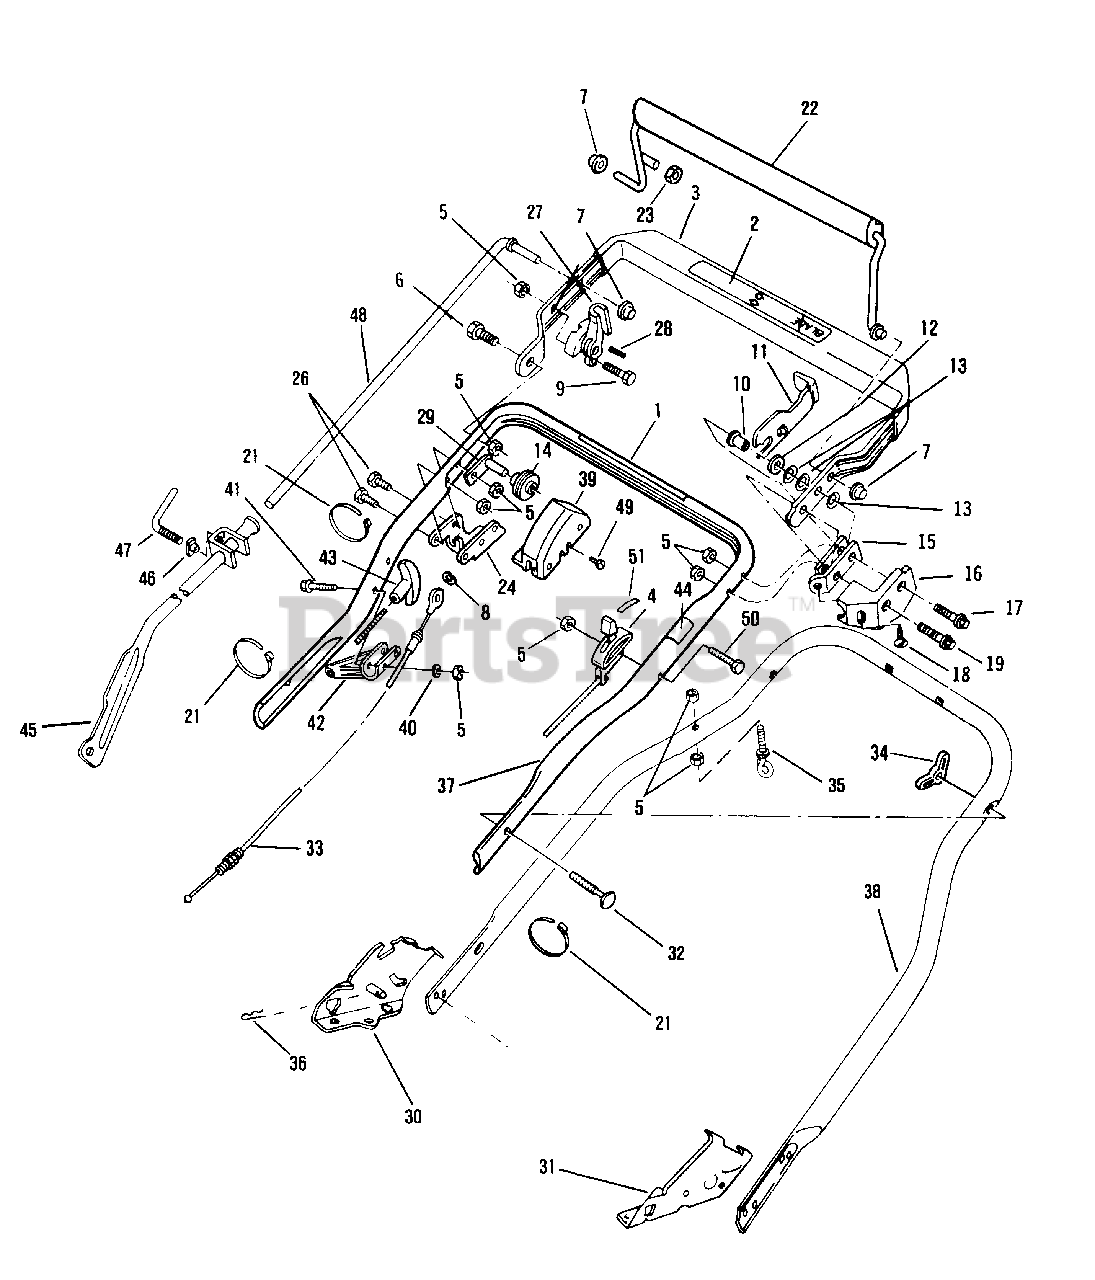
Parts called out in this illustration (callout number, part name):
1	Decal-Starting Instructions
2	Decal-Engine/Blade Control
3	Top Handle and Doubler Assembly
4	Control Assembly-Throttle
5	Locknut
6	Bolt-Shoulder-R.H.
7	Pushnut
8	Retaining Ring-Cable
9	Hex-Washer Head Shoulder Bolt
10	Spacer-Flanged
11	Lever-Lockout
12	Washer-Plain
13	Washer-Spring
14	Pulley
15	Down Stop
16	Guard-Lockout
17	Bolt-Shoulder
18	Screw
19	Bolt-Shoulder-L.H.
21	Tie Strap
22	Control Lever and Nut Assembly
23	Nut-Acorn
24	Bracket-Clutch Cable
26	Screw-Clutch Cable Bracket
27	Cam and Roll Pin Assembly
28	Roll Pin
29	Pivot-Bracket-Pulley
30	Handle Bracket-R.H.
31	Handle Bracket-L.H.
32	Screw
33	Control Cable Assembly
34	Knob
35	Eyebolt
36	Hair Pin-Handle Bracket
37	Handle Section-Center
38	Handle Section-Bottom
39	Cover
40	Washer-Plain
41	Screw-Truss Head
42	Rope Guide Assembly
43	Handle-Starter
44	Decal-Drive Lockout
45	Control Lever Assembly
46	Nut-Control Lever Clamp
47	Lever-Rod Clamp
48	Rod-Control
49	Screw-Hex Head
50	Screw
51	Decal-Throttle Control
